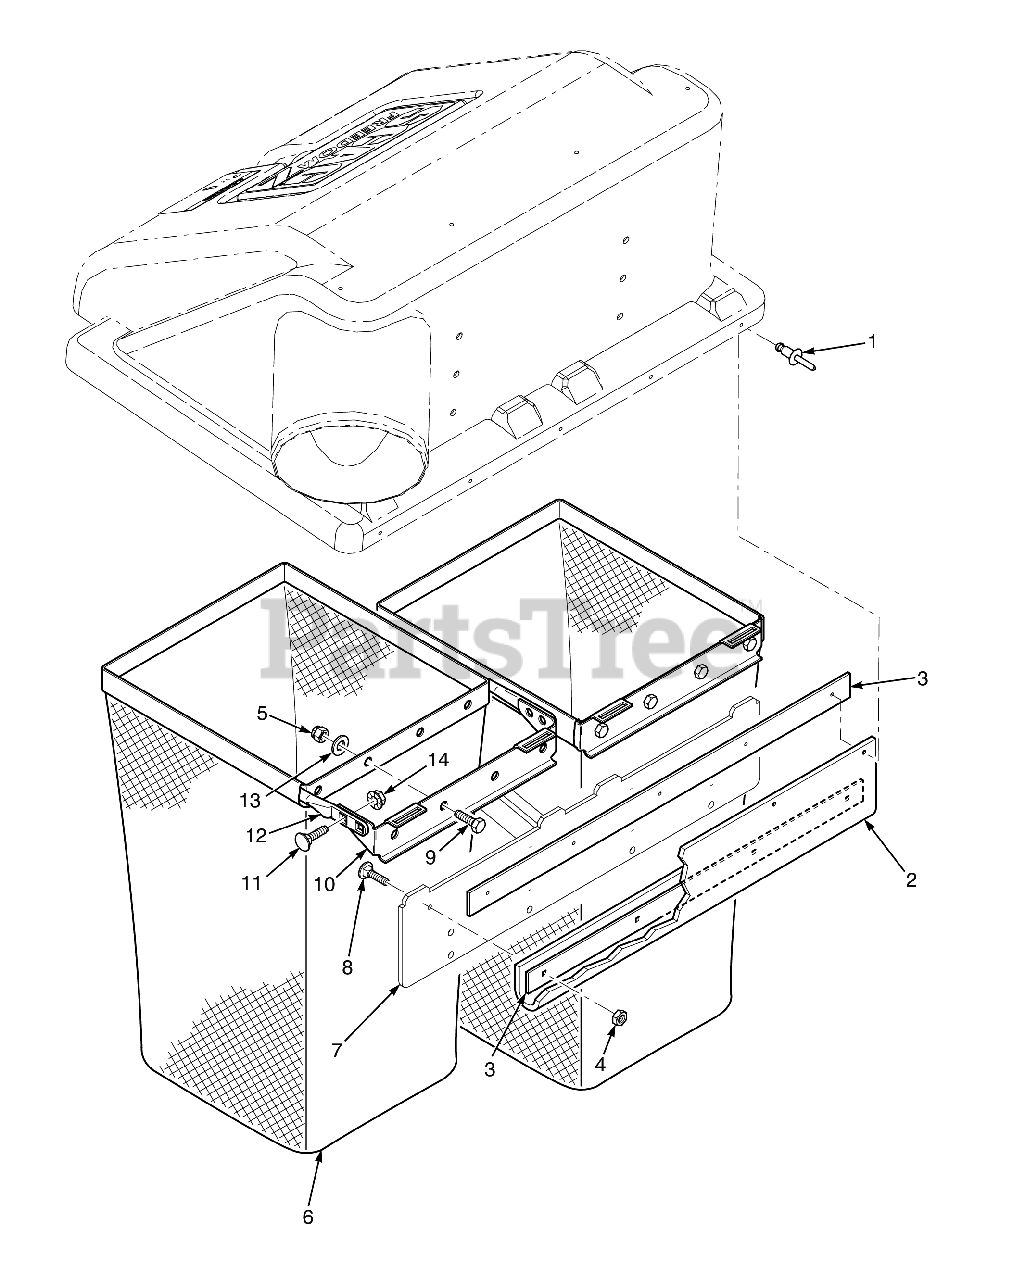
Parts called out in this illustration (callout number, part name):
1	Pop Rivet, 3/16 x .652"
2	Diode (part of wire harness)
3	Retainer, Seal
4	Bolt, Hex Hd. 1/2-13 x 9-1/2"
5	HEX NUT, ELASTIC STOP LOCK, 5/16-18
6	Bag Assembly
7	Frame Weldment, Bag Support
8	BOLT, HEX HEAD, 1/4-20 X 3/4 GR.5
9	BOLT, SERRATED FLANGE HEX HEAD 5/16-18 X 3/4"
10	Mount, Bag Frame Tube
11	Bolt, 5/16-18 x .75 RHSN Carriage
12	Tube, Bag Support
13	Flatwasher, 5/16-.375 x .875 x .083 (35BV & 37BV-EFI)
14	Nut, Serrated Flange 5/16-18 (Right Front Engine Mounting, Briggs and Kohler Only)
